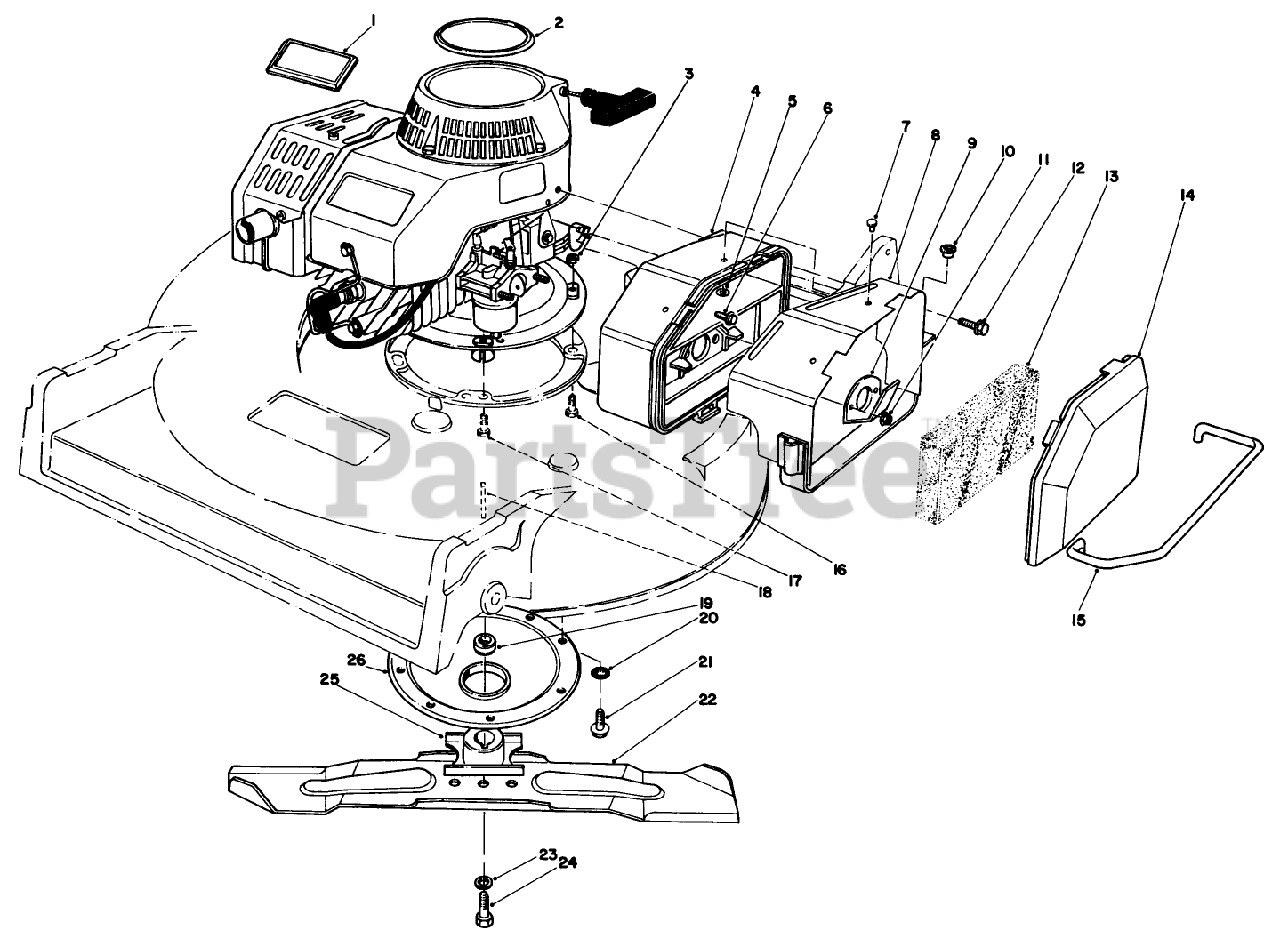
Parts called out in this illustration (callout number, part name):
3	NUT-JAM
4	AIR CLEANER ASM
5	WASHER-FLAT
7	RIVET-POP
9	SPIT BACK DEFLECTOR
12	SCREW-HHF
13	FILTER
15	AIR CLEANER GUARD*
16	SCREW-HH
17	SCREW-HH
18	KEY-SQUARE
19	SPACER-BLADE RETAINER
20	WASHER-LOCK, INTERNAL
21	SCREW-THD ROLL, HWH
23	WASHER-LOCK
24	SCREW-BLADE
26	PROTECTOR-CRANKSHAFT
